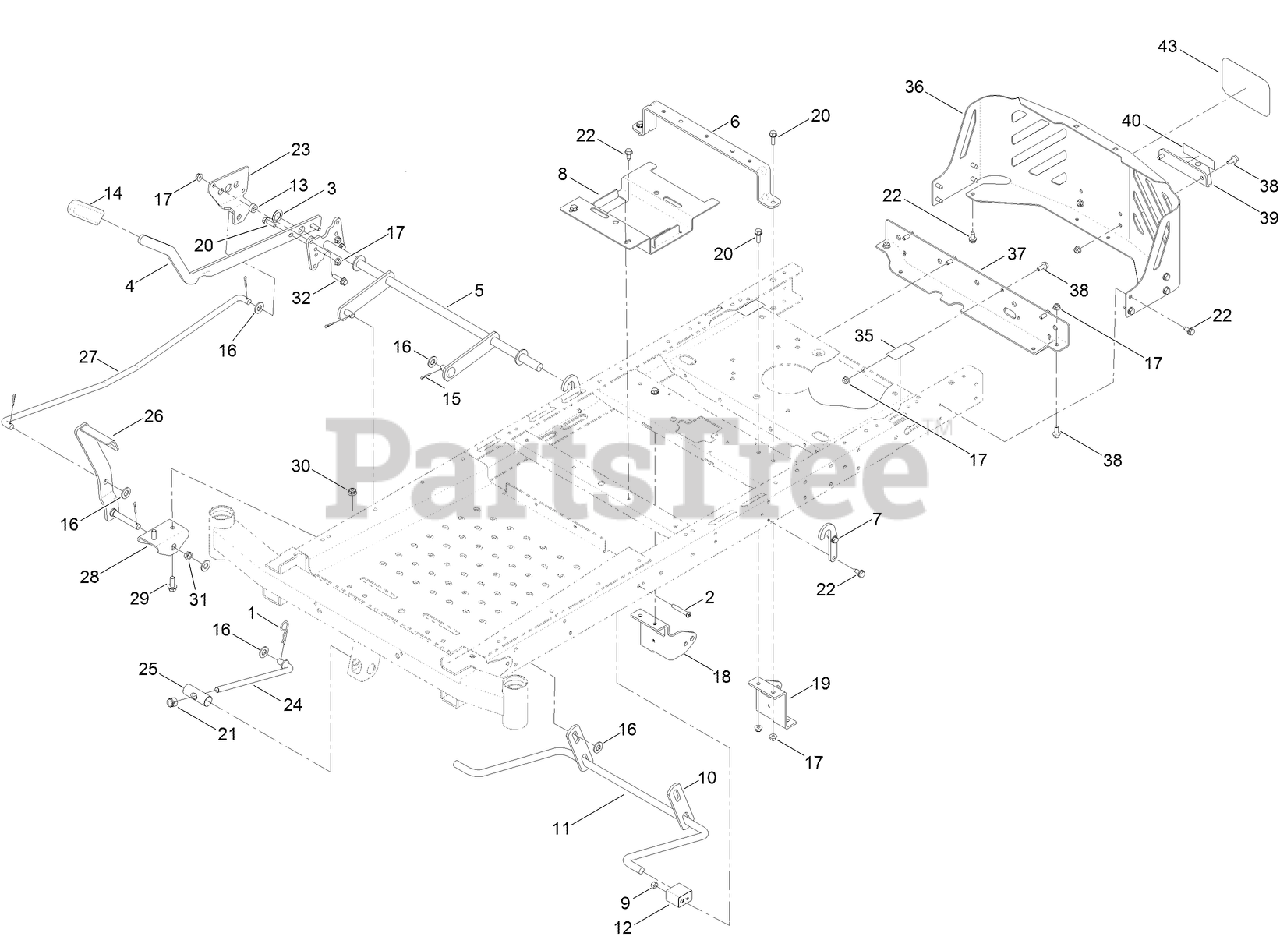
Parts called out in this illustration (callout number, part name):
1	PIN-COTTER
2	SCREW-HSBH
3	WASHER-THRUST
4	LEVER-LIFT
5	LIFT-DECK, WIDE
6	BRACE-SEAT, REAR
7	BRACKET-LIFT
8	BRACKET-BATTERY
9	NUT-LOCK, NI
10	LINK-LIFT
11	ARM-LIFT, REAR (WIDE)
12	BLOCK-PIVOT
13	SPACER
14	GRIP-LEVER
15	PIN-COTTER
16	WASHER-FLAT
17	NUT-HF, NI
18	MOUNT-HYDRO, FRONT (RH)
19	MOUNT-HYDRO, FRONT (LH)
20	SCREW-HHF
21	NUT-HEX
22	SCREW-HWHTF
23	PLATE-FOOTLIFT
24	ROD-MOUNT, DECK
25	PIN-PIVOT
26	PEDAL ASM
27	ROD-FOOTLIFT
28	BRACKET-FOOTLIFT
29	SCREW-HHF
30	NUT-HF, NI
31	BUSHING-FLANGE
32	SCREW-HHF
35	DECAL-BYPASS
36	GUARD-ENGINE, WIDE
37	CROSSMEMBER-REAR, WIDE
38	SCREW-HHF
39	BRACKET-HITCH
43	DECAL
